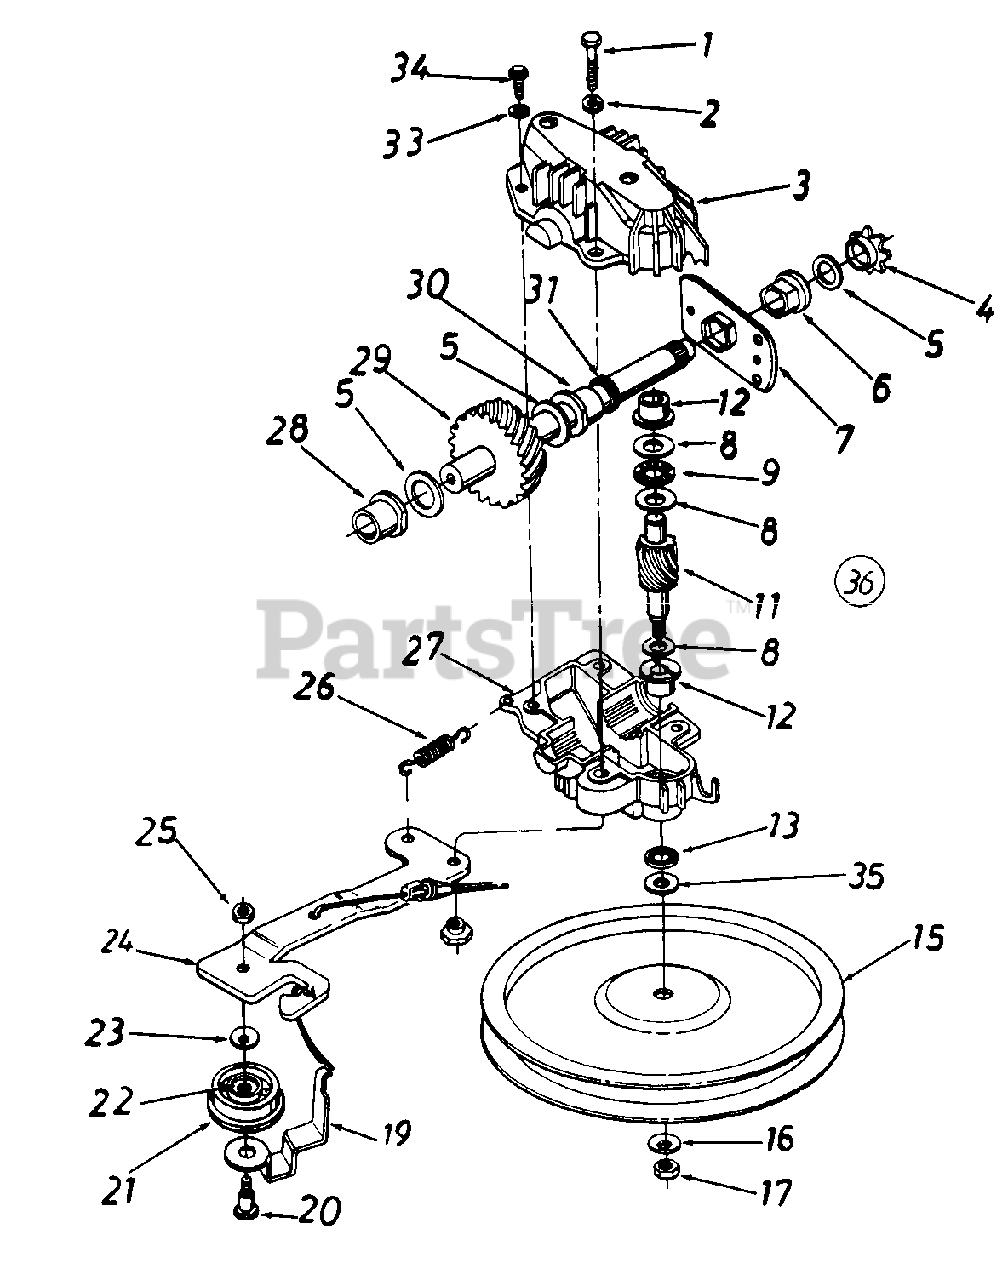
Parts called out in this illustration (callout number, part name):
1	Hex Bolt 1/4-20 x 1.25" Lg w/Patch
2	L-Wash 1/4" I.D.
3	Upper Hsg. Half
4	#48 Sprocket 7 Tooth x 1/2 Pitch
5	Fl-Wash 5/8" I D x 030
6	Hex Flange Brg. .631" I.D
8	Thrust Wash..382" I D. x 70" O.D.
9	Thrust Bearing .375" I.D. x .812" O.D.
11	11 Tooth Pinion Shaft
12	Flange Bearing
15	Fl-Pulley 5.06" 0 D
16	Bell-Wash. 265" I.D. x.75"
17	Hex L-Nut 1/4-28 L.H. Thd.
19	Belt Guard
20	Shld. Bolt 375" Dia x 40"
21	Fl-Idler Plastic 1 50" Dia.
22	Needle Brg. .375" x .31
23	Bell-Wash. 265" I.D x 75"
24	Idler Brk't Ass'y
25	Hex Patch L-Nut 1/4-28 Thd
26	Extension Spring 1.12" Lg.
27	Lower Hsg. Half
28	Flange Bearing .566 Dia
29	Shaft Ass'y.
30	Flange Bearing .629 Dia
31	Oil Seal .625 Dia.
33	L-Wash. #10 I.D.
34	Hex Tap Scr #10 x 62" Lg
35	Hex Washer .26" x 88"
